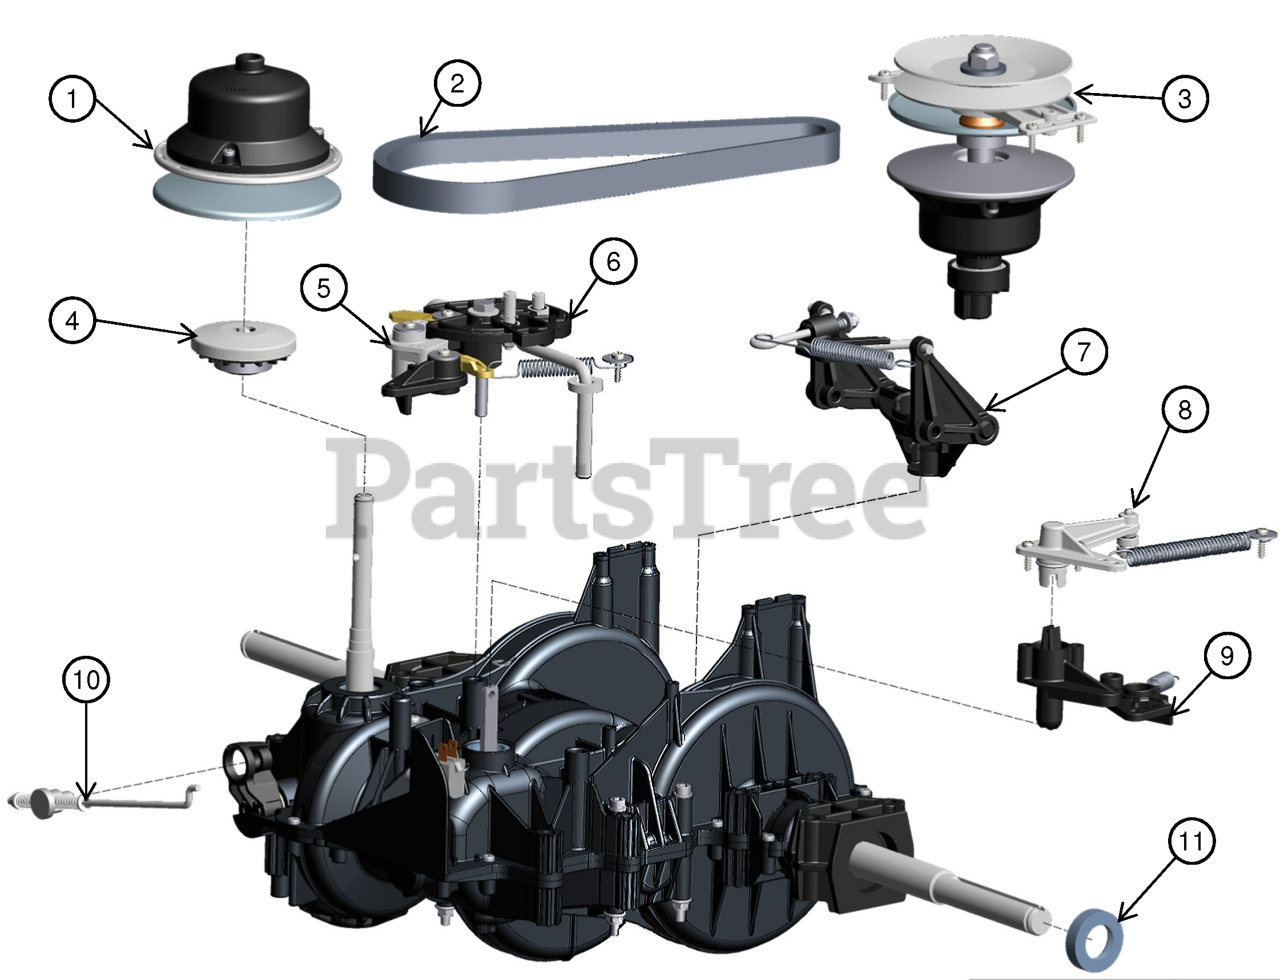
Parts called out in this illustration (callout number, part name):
1	DRIVEN KIT RS800
2	VARIATION BELT TXL
3	DRIVER KIT RS800 GT79260
4	INVERSION SECURITY SYSTEM
5	CONTROL KIT RS800 P
6	CONTROL CAM RS800 P
7	VARIATION KIT
8	BRAKE KIT 79255
9	BYPASS KIT
10	INVERSION KIT
11	OUTPUT SEAL RS800
12	COVER RS800 P
